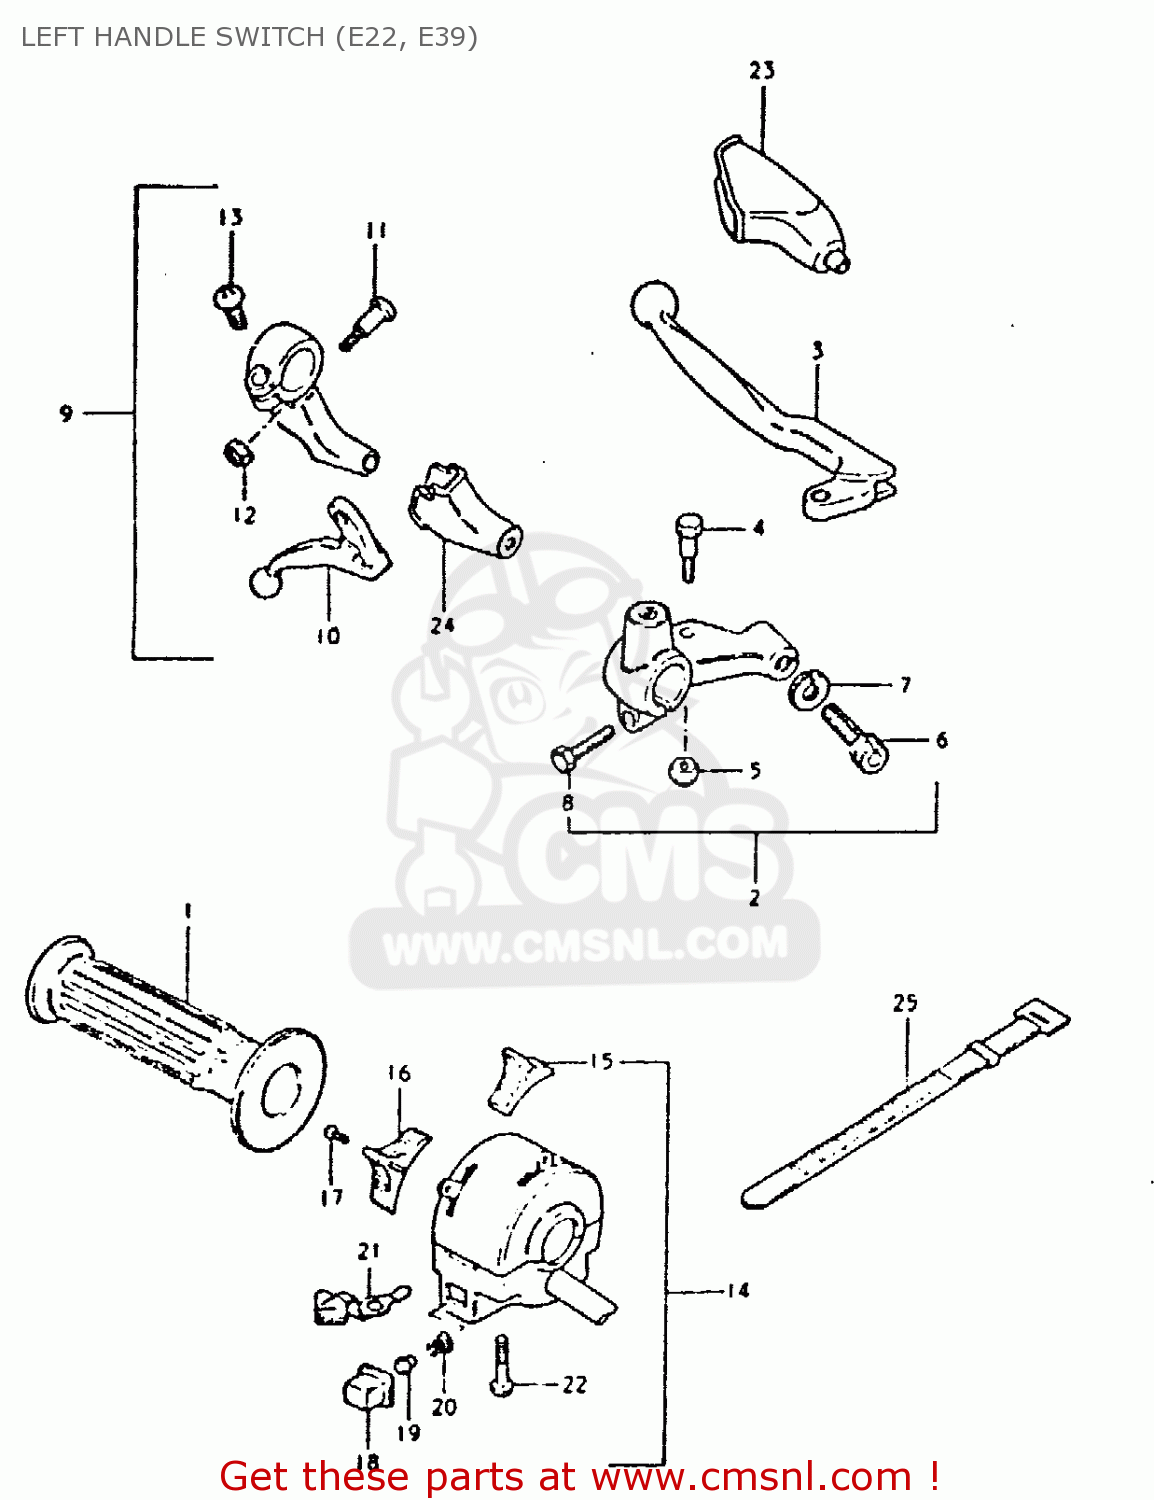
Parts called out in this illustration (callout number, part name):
1	GRIP,L
2	LEVER ASSY,CLUTCH
3	LEVER,CLUTCH
4	BOLT,LEVER
5	NUT 6MM
6	ADJUSTER,CABLE
7	NUT,CABLE ADJUSTER
8	BOLT
9	LEVER ASSEMBLY,DECOMPRESSION
10	LEVER,DECOMPRESSION
11	BOLT,LEVER
12	NUT,LEVER BOLT
13	SCREW
14	SWITCH ASSY, HANDLE LH
15	KNOB,LIGHTING SWITCH
16	KNOB, DIMMER
17	SCREW
18	BUTTON,HORN
19	CONTACT
20	SPRING
21	KNOB,TURNSIGNAL
22	SCREW
23	COVER,CLUTCH LEVER
24	COVER,DECOMP LEVER DUST
25	CLAMP(L:120)
